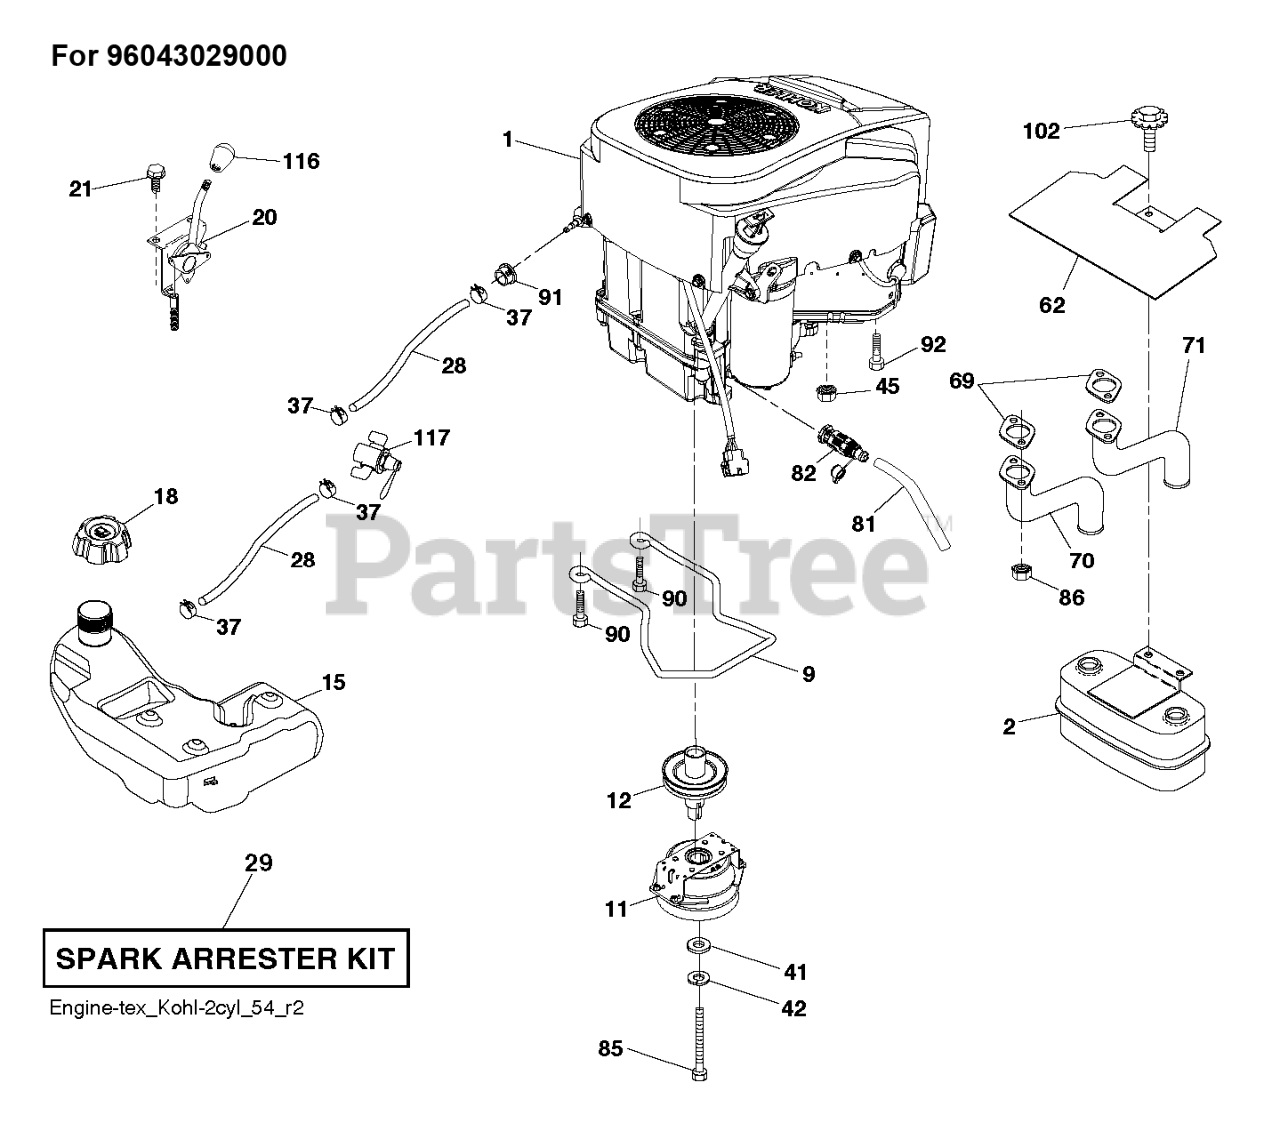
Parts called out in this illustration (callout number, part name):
2	MUFFLER.ASM.TWIN.MNTG.BRACKET
9	KEEPER.BELT.ENG.4.25"2.BLT.431
11	CLUTCH.OGURA.5.0PD.GT1.5A-EH01
12	PULLEY.EXTENDED.SHAFT.GROUND
15	Tanks
18	FUEL CAP
18	CAP ASSY FUEL 3" GRAY
20	CONTROL.THROTTLE.PRO.
21	SCREW.#10 X 0.750.BOS
28	LINE.FUEL.64"REAR.EMIS
29	KIT.SPARK ARRESTOR 794945 B&S
37	HOSE CLAMP
42	WASHER 7/16 LOCK
45	NUT HEX_LRG FLG_1_4-20_LOCK
62	SHIELD.HEAT.MUFFLER
70	TUBE.EXHAUST.LH.FR961/FR730
71	TUBE.EXHAUST.RH.FR961/FR730
81	TUBE, DRAIN OIL ASM.
82	VALUE.OIL.DRAIN
85	BOLT.HEX.7/16-20X3.GR5.YELLOW
86	NUT.HEX.FLANGE.TOPLOCK
90	SCREW 3/8-16X1
91	BUSHING.1.375OD
92	SCREW 3/8-16X1
102	SCREW
116	KNOB - SHIFT
117	VALVE FUEL RESERVE
